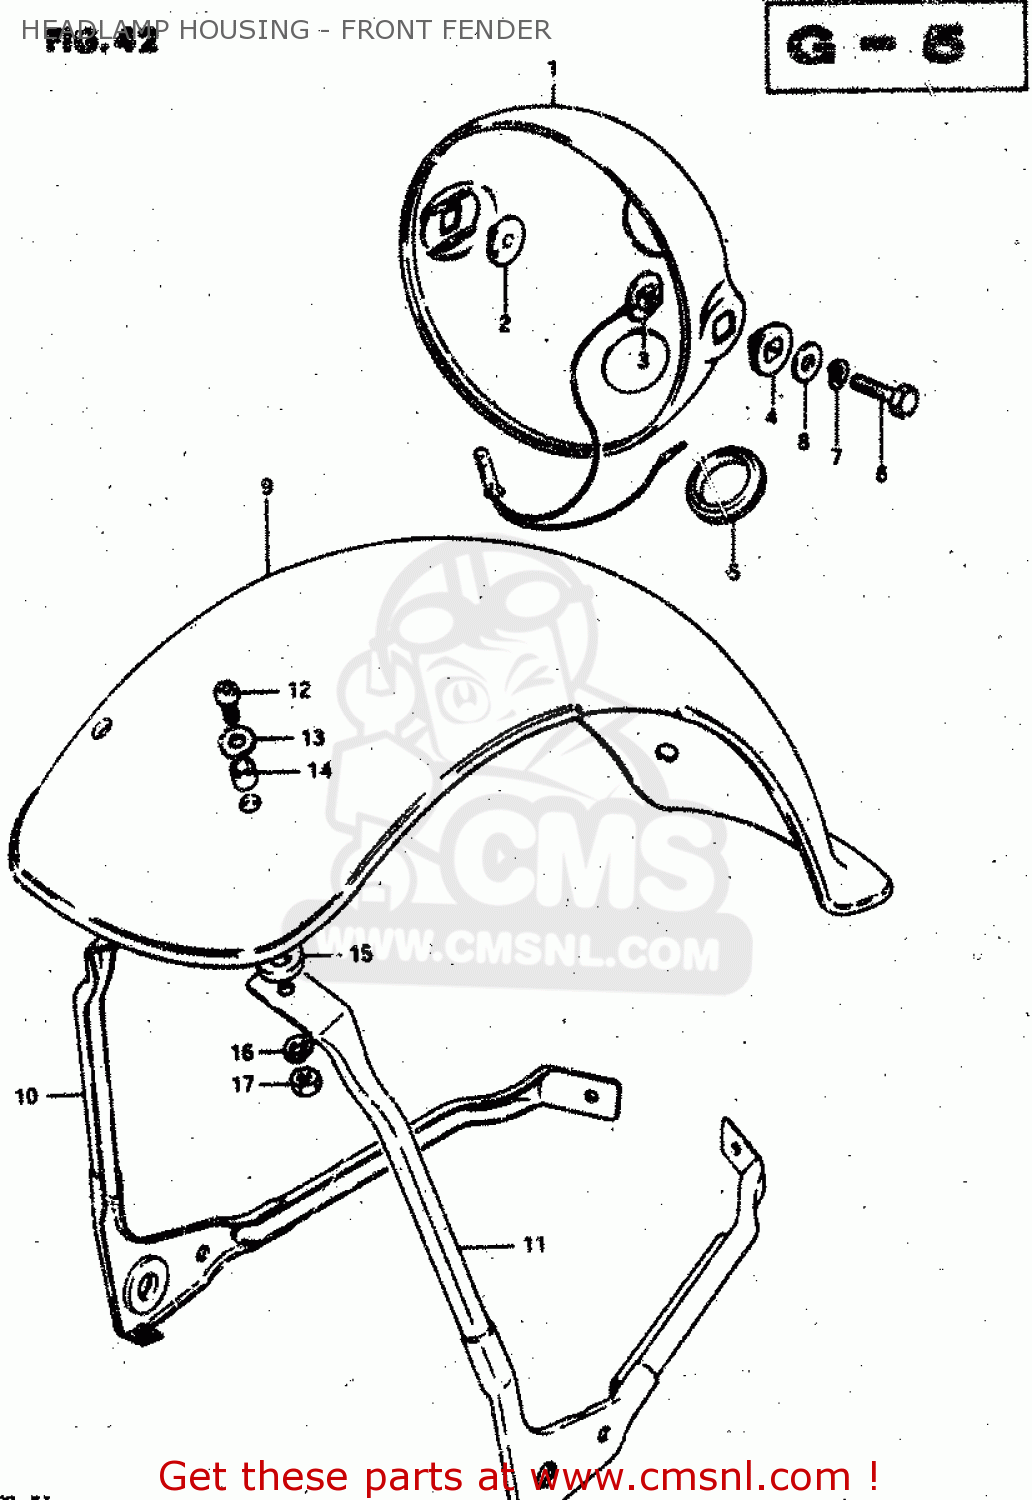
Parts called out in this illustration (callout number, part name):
1	HOUSING, HEADLAMP
2	SPACER,HEADLAMP HOUSING
3	SPACER
4	CUSHION
5	GROMMET,HEADLAMP HOUSING
6	BOLT
7	LOCK WASHER
8	WASHER
9	FENDER, FRONT
10	BRACE, FRONT FENDER RH
11	BRACE, FRONT FENDER LH
12	SCREW
13	WASHER
14	SPACER (5.5X9.5X6.5)
15	CUSHION
16	LOCK WASHER
17	NUT
